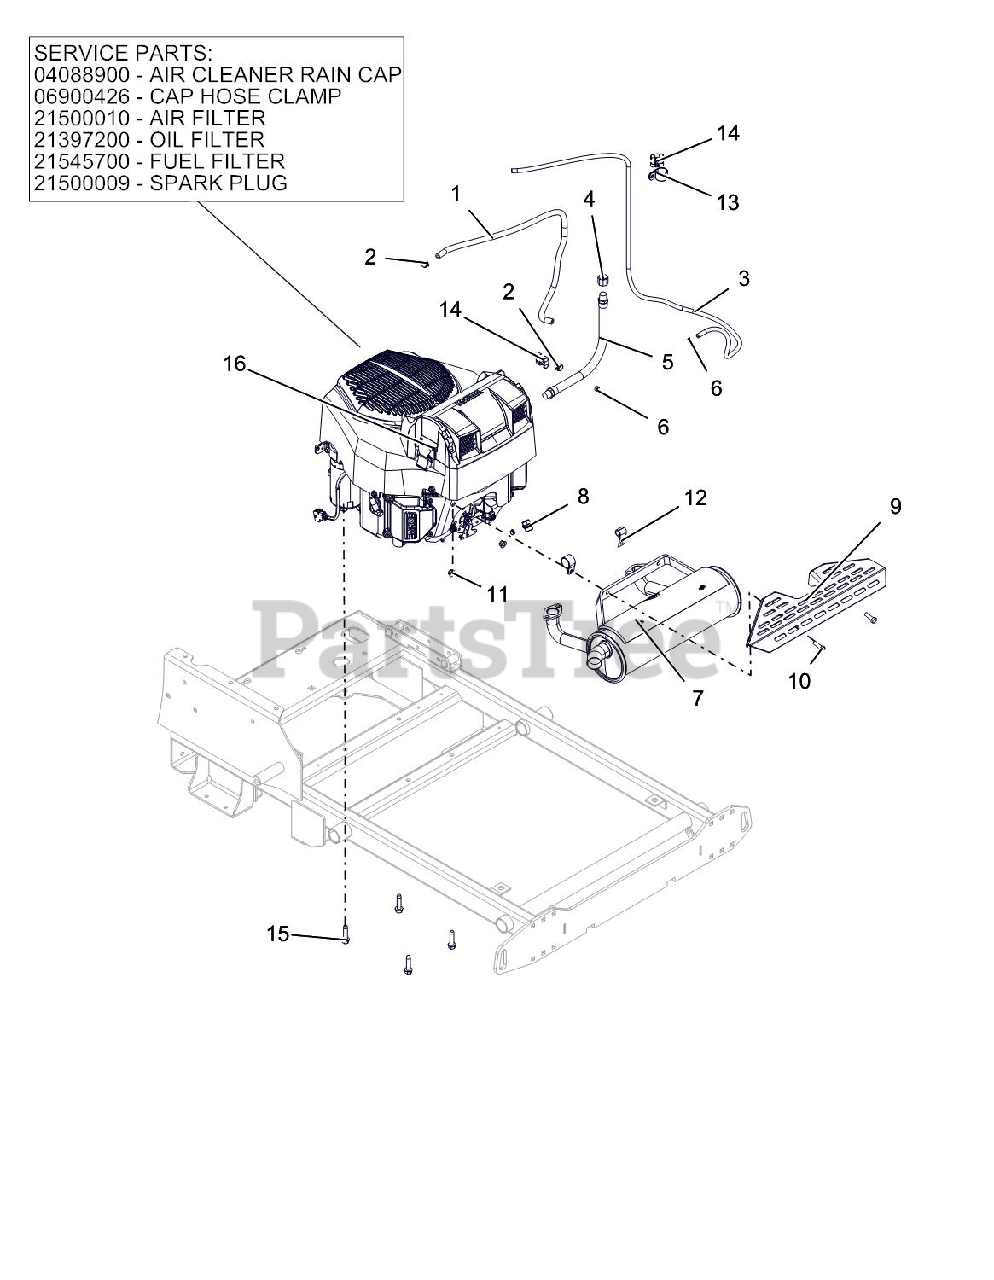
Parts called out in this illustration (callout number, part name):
1	HOSE, .25 LOW-PERM BULK GAS
2	CLAMP, FUEL LINE
3	HOSE, .188 LOW-PERM BULK GAS
4	PIPE CAP 3/8 NPT FEMALE
5	HOSE,HYD .38-14-0K M6N0-M6N0
6	CLAMP-HOSE, SPRING .188
7	MUFFLER, KOHLER EFI PRO-STANCE
8	PLUG, EXHAUST
9	GUARD, MUFFLER
10	@BLT-HEX .31-18X1.00 GR5 YWZC
11	@NUT-LK-NYL-FLG .31-18 YWZC
13	CLAMP, COUSHIONED STEEL REV
14	CLIP, T, .38-.50
15	@SCR-TAP .38-16X1.50 HWH TR YZ
16	FILTER, OIL - KOH CV20
16	CAP, KAW 11065-7025
16	CLAMP, HOSE #36 SS 1.813-2.75
16	ENGINE, KOHLER ZT730
16	AIR CLEANER, KOHLER CONFIDANT
16	FILTER-FUEL KOHLER COURAGE PRO
16	PLUG, SPARK KOHLER
